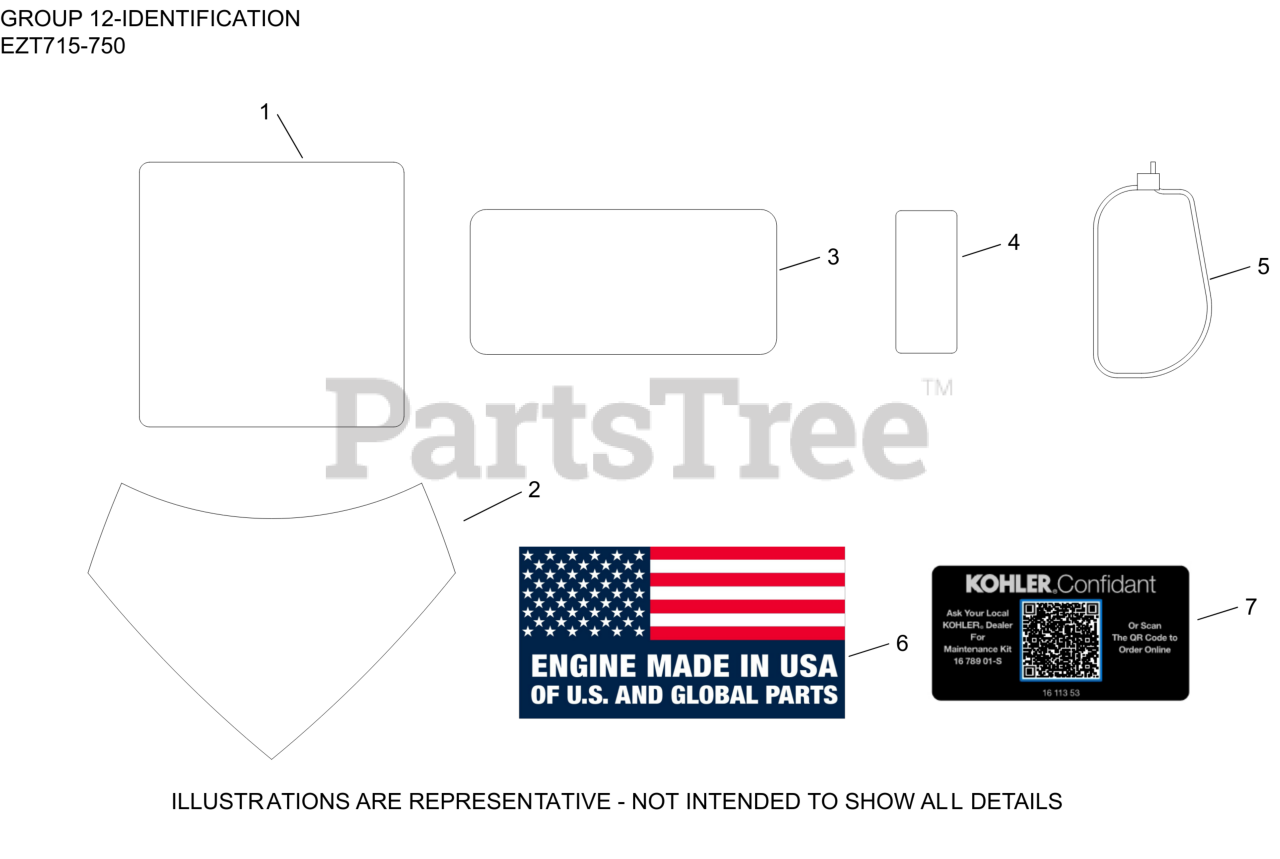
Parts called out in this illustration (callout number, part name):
2	LABEL, CONFIDANT (27HP, LPAC)
3	LABEL, CANADIAN COMPLIANCE
4	LABEL, CLEAR LAMINATION
6	DECAL, USA
